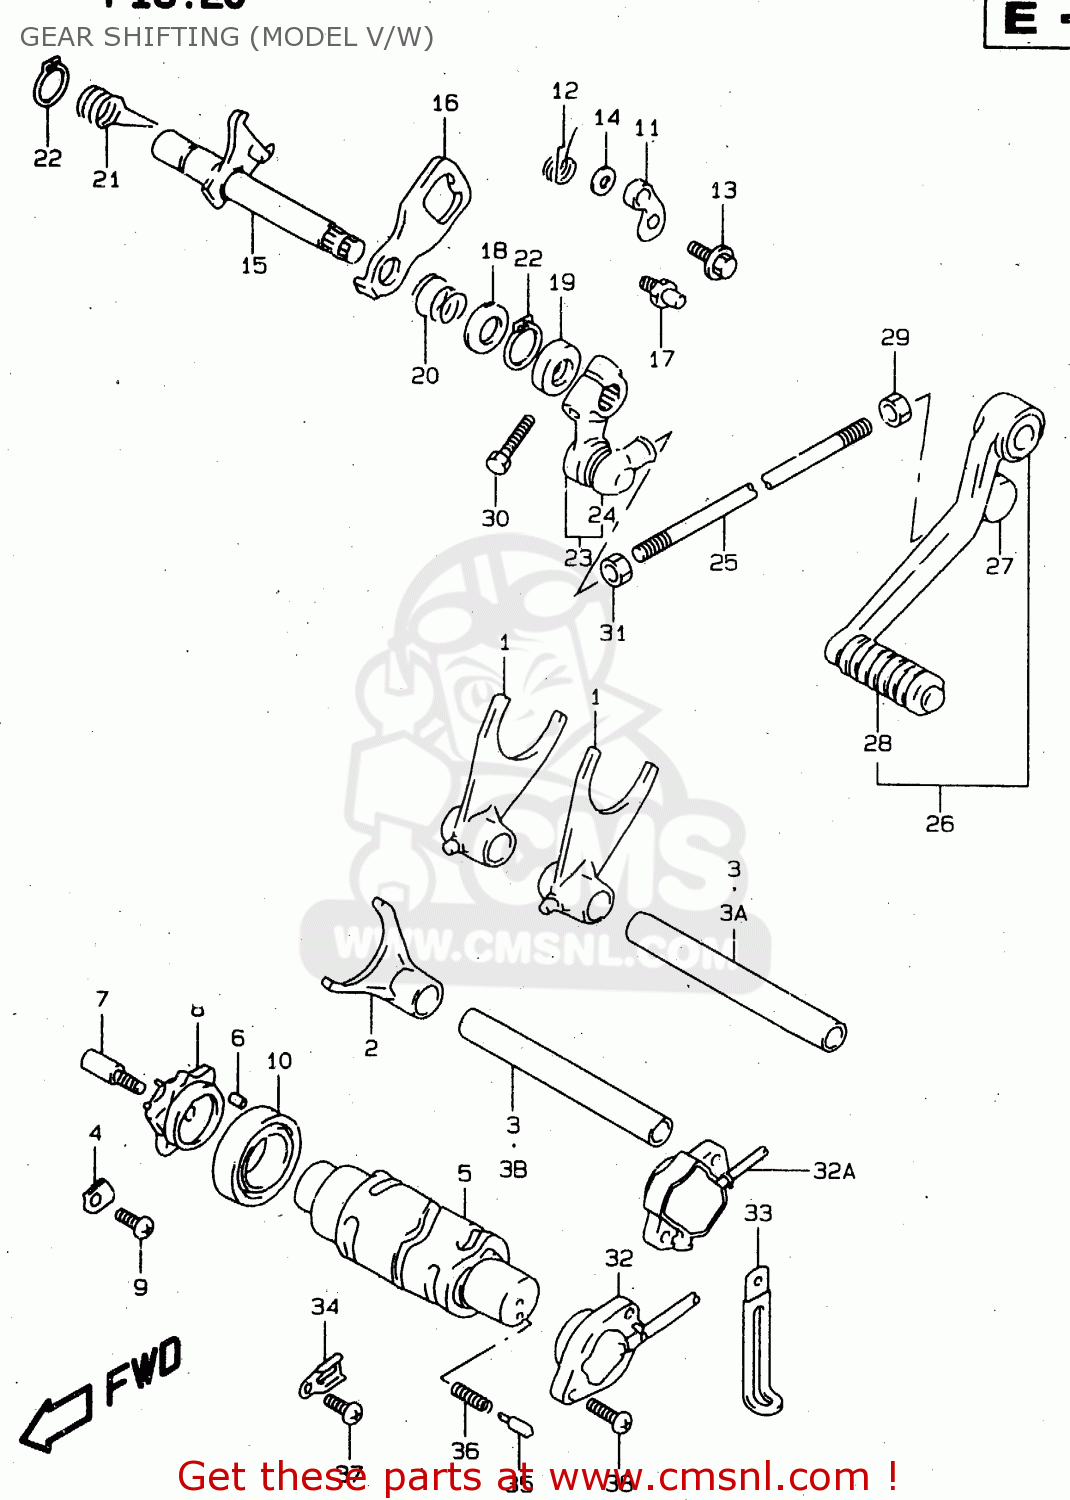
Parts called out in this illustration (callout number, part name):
1	FORK,GEAR SHIFT
2	FORK,GEAR SHIFT NO.3
3	SHAFT,GEAR SHIFT FORK(L:115)
3A	SHAFT,GEAR SHIFT FORK
3B	SHAFT,GEAR SHIFT FORK NO.2
4	RETAINER
5	CAM,GEAR SHIFT
6	PIN
7	PIN,SHIFT CAM DRIVEN GEAR
8	PLATE,GEAR SHIFT CAM
9	SCREW
10	BEARING
11	STOPPER,GEAR SHIFT CAM
12	SPRING,SHIFT CAM STOPPER
13	BOLT(6X14.3)
14	WASHER
15	SHAFT,GEAR SHIFT
16	PLATE,GEAR SHIFT CAM DRIVE
17	STOPPER,GEAR SHIFT CAM
18	SHIM(14X22X1)
19	SEAL,OIL(14X22X6)
20	SPRING
21	SPRING
22	CIRCLIP
23	ARM,GEAR SHIFT LINK
24	COVER,DUST
25	ROD,GEAR SHIFT LINK
26	LEVER ASSY,GEAR SHIFT
27	COVER,DUST
28	RUBBER,GEAR SHIFT PEDAL
29	NUT
30	BOLT
31	NUT
32	BASE ASSEMBLY,GEAR SHIFT TERMINAL
32A	BASE ASSY,GEAR SHIFT TERMINAL
33	CLAMP(L:65)
34	CLAMP,GENERATOR LEAD WIRE
35	PIN(5X15.5)
36	SPRING
37	SCREW
38	SCREW
